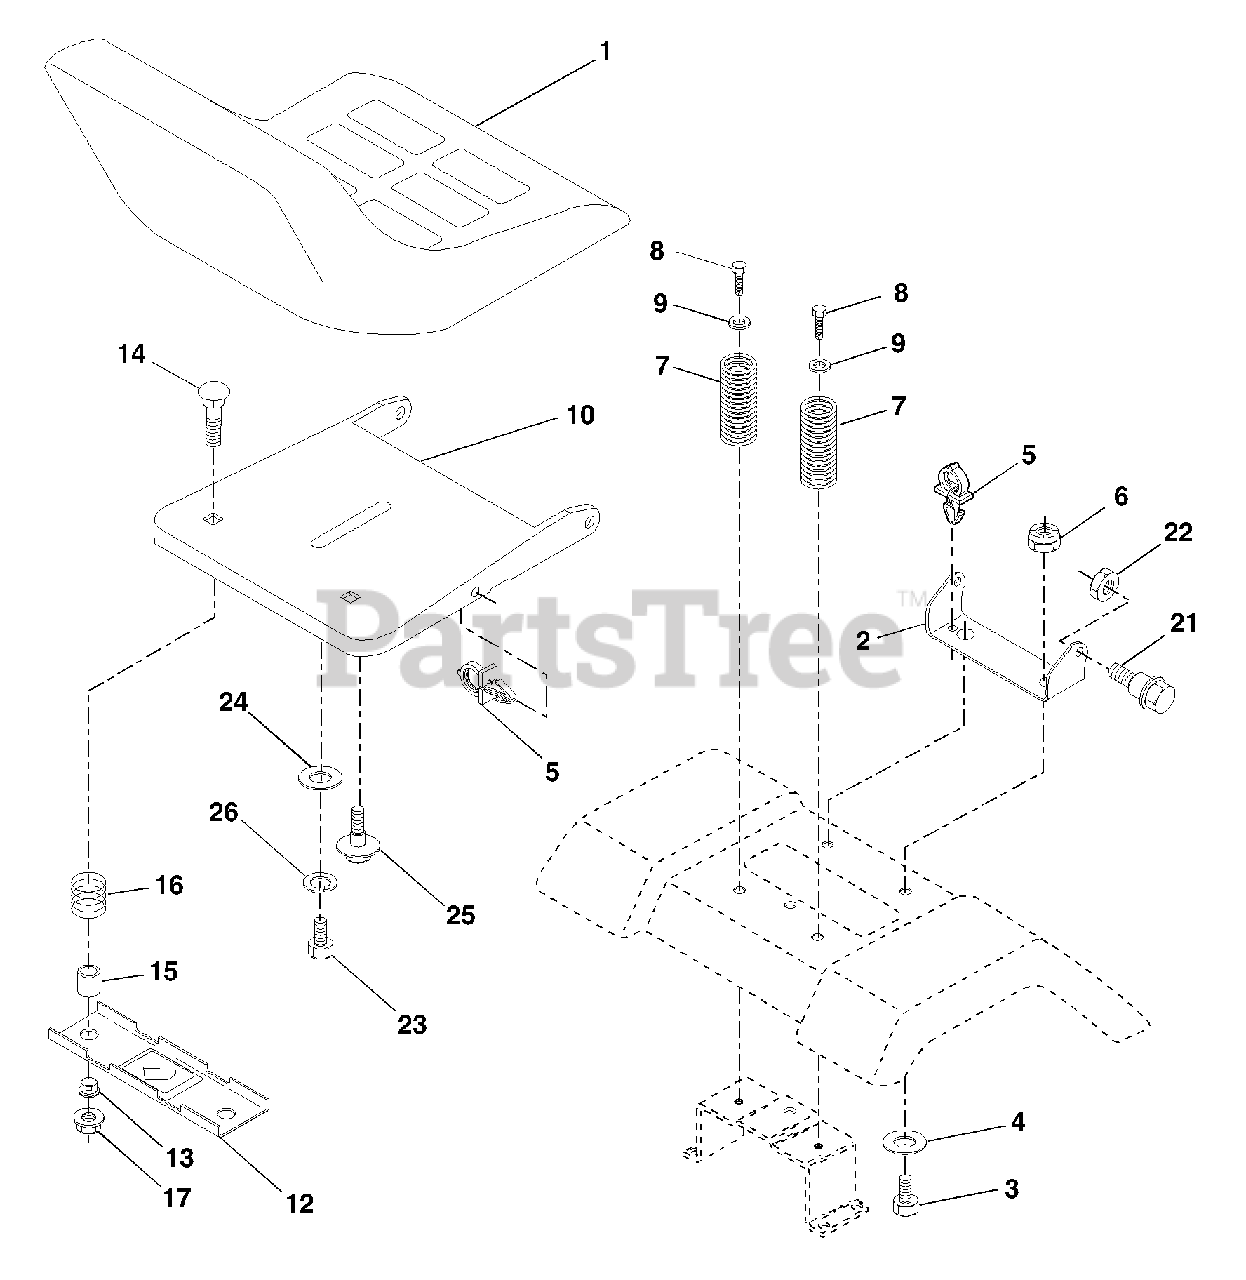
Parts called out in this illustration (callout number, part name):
1	Seat
2	Bracket Seat Pivot
3	Bolt Hex 3/8 - 16 X 1
4	Washer 13/32 X 1 X10Ga.
5	Clip Push-In Hinged
6	Nut Lock Hex w/Ins 3/8 - 16
7	Spring Seat Cprsn 2 250 Blk Zi
8	Screw 3/8-16 x 1.5
9	Washer 13/32 X 1 X 14 Ga
10	Pan Pnt Seat (Blk)
12	Bracket Pnt Mounting Switch
13	Bushing Snap Blk Nyl
14	Bolt Rdhd Sht Nk 1/4 - 20 X 1 -1/2
15	Spacer Split .28 X .96
16	Spring Cprsn
17	Nut Lock 1/4 Lge Flg
21	Bolt Shoulder 5/16-18 Unc-2A
22	Nut Lock Hex w/Ins 5/16 - 18
23	Bolt Hex Black
24	Washer 17/32 X 1-3/16 X 12 Ga
25	Bolt Shoulder 5/16-18 X .62
26	Washer Lock Hvy Hlcl Spr 1/2
